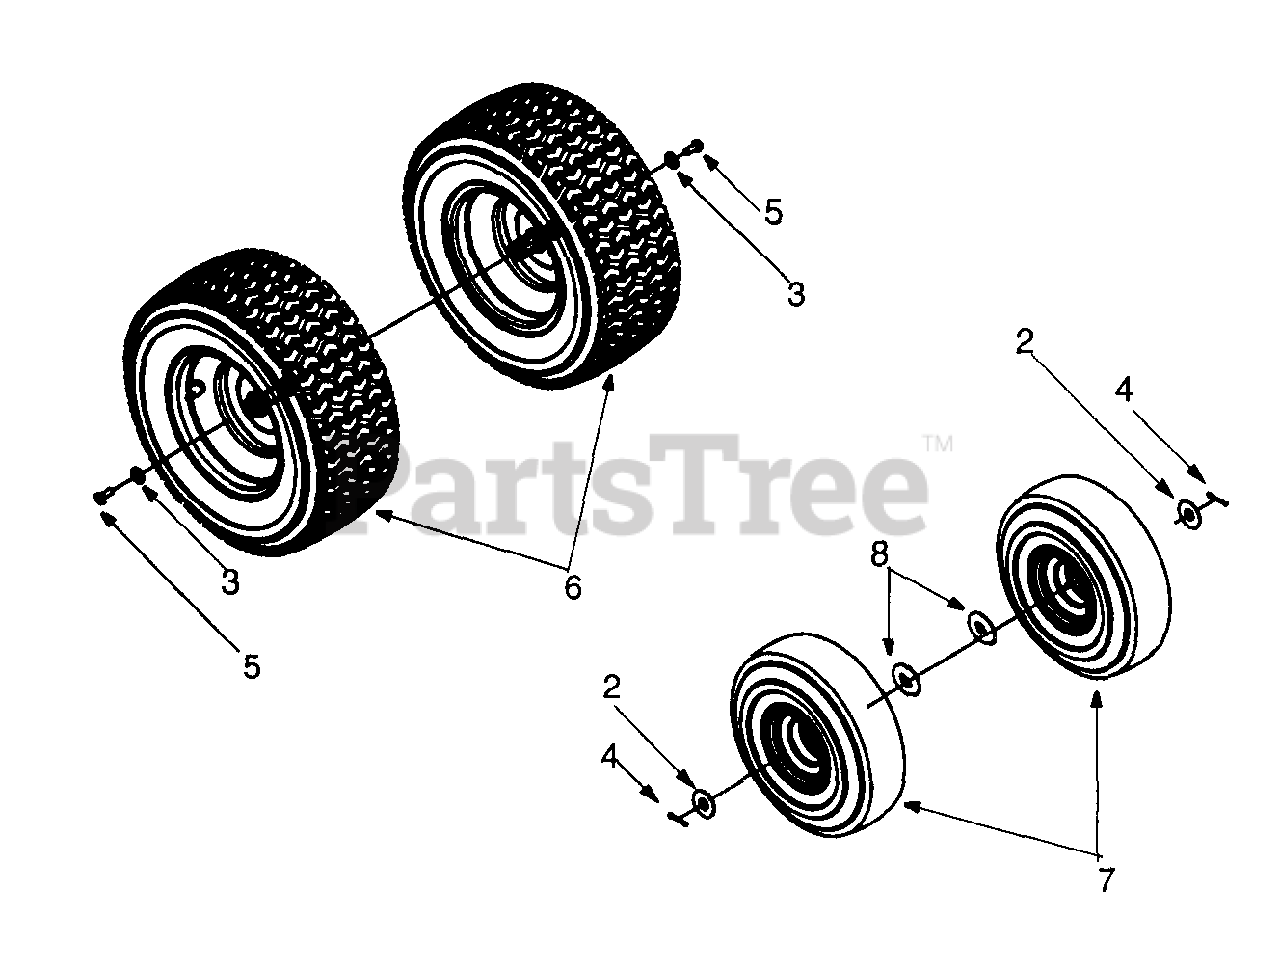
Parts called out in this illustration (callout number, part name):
2	Flat Washer .635 x 1.589 x .060
3	Bell Washer .345 I.D. x .88 O.D. x .06
4	Hairpin Clip
5	Hex Screw 5/16-24 x .75
